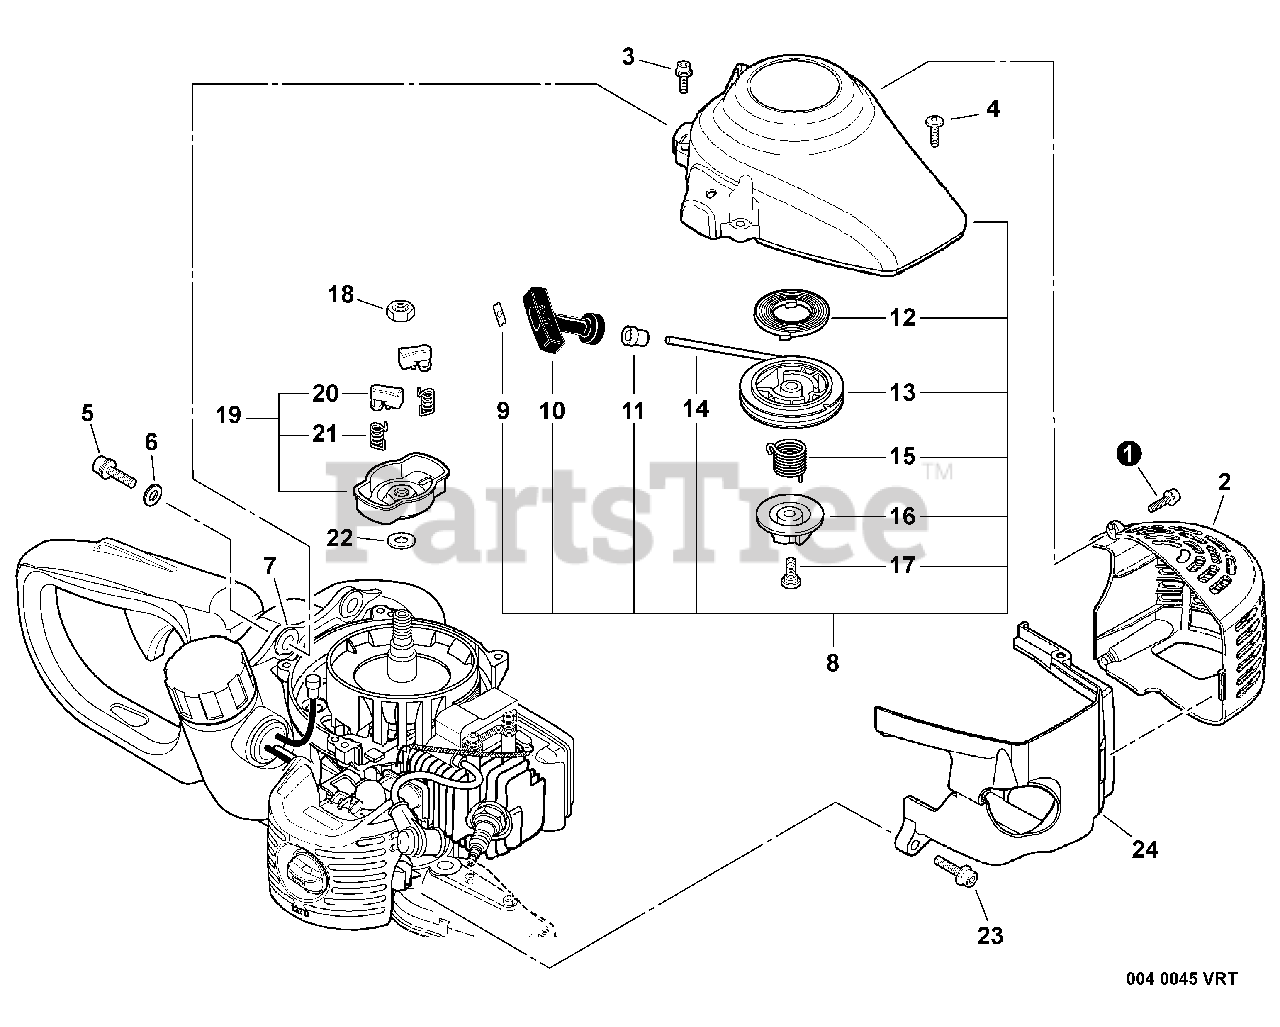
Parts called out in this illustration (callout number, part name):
1	SCREW - 5X16
2	COVER, EXHAUST
3	SCREW - 4X16
4	SCREW - 4
5	SCREW - 5X20
6	WASHER - 5
7	COLLAR - 5
8	STARTER ASSY
9	RETAINER, ROPE
10	GRIP, STARTER
11	GUIDE, ROPE
12	SPRING, REWIND
13	REEL, ROPE
14	ROPE, STARTER - 3X700
16	CATCHER, PAWL
17	SCREW
18	NUT - LEFT HAND
19	STARTER PAWL ASSY
20	PAWL, STARTER
21	SPRING, RETURN
22	WASHER - 8
23	SCREW - 5X16
24	COVER, ENGINE
